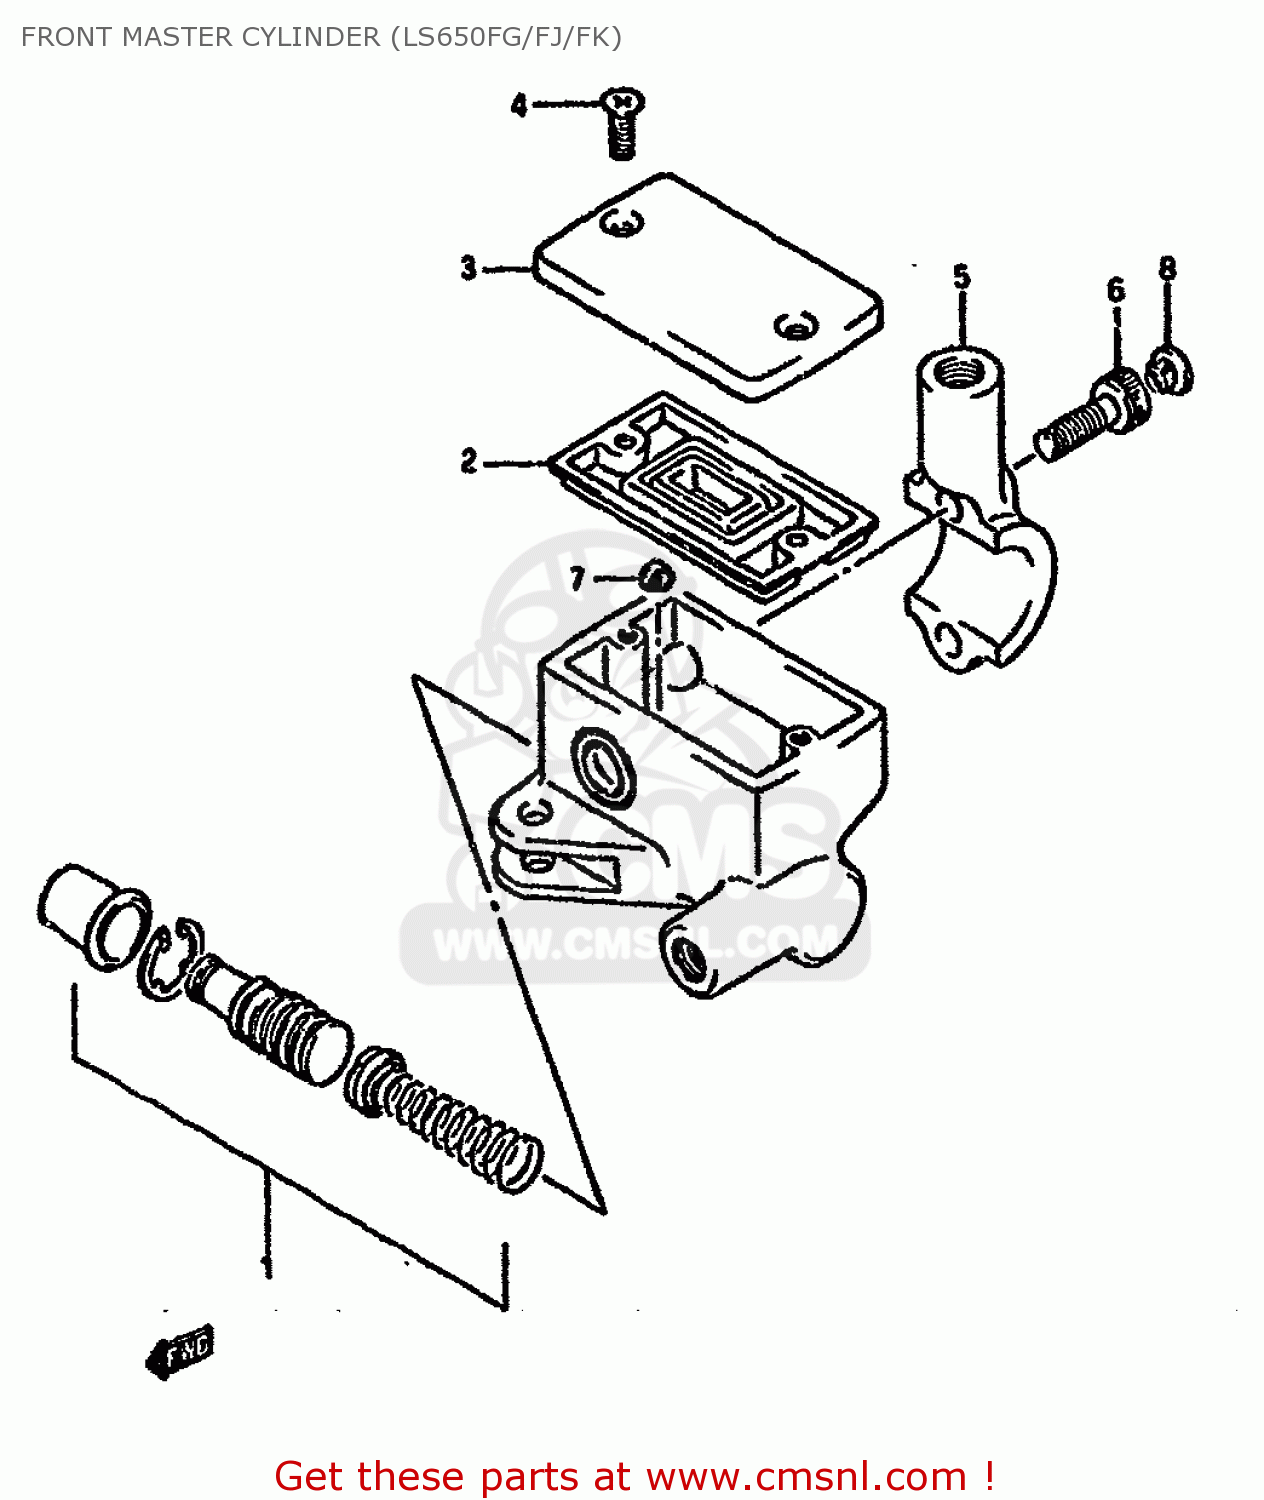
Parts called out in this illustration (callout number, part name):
1	CUP SET,MASTER CYLINDER
2	3-1
3	CAP
4	SCREW,RESERVOIR CAP
5	HOLDER
6	BOLT ,6X20
7	PROTECTOR
8	CAP(OD:10)
